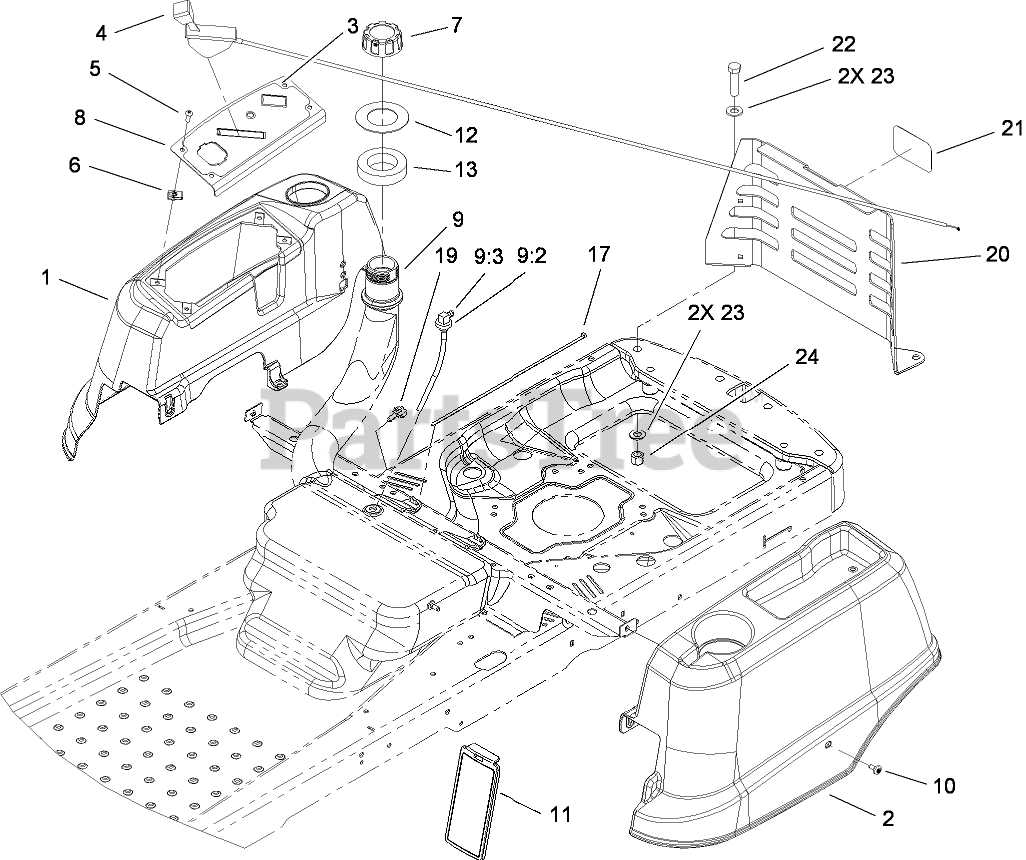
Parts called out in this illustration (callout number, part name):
1	POD-RH
2	POD-LH
3	DECAL-PANEL, CONTROL
4	CABLE-THROTTLE
5	SCREW-PRH
7	CAP-GAS
8	PANEL-CONTROL
9	FUEL TANK ASM
9:2	BUSHING
9:3	FITTING-90 DEGREE
10	SCREW-SHOULDER
11	COVER-CONTROL
12	WASHER-RUBBER
13	SEAL-FOAM
17	TIE-CABLE
19	CLIP-HARNESS
20	SUPPORT-COVER, REAR
21	DECAL
22	SCREW-HH
23	WASHER-FLAT
24	NUT-LOCK, NI
